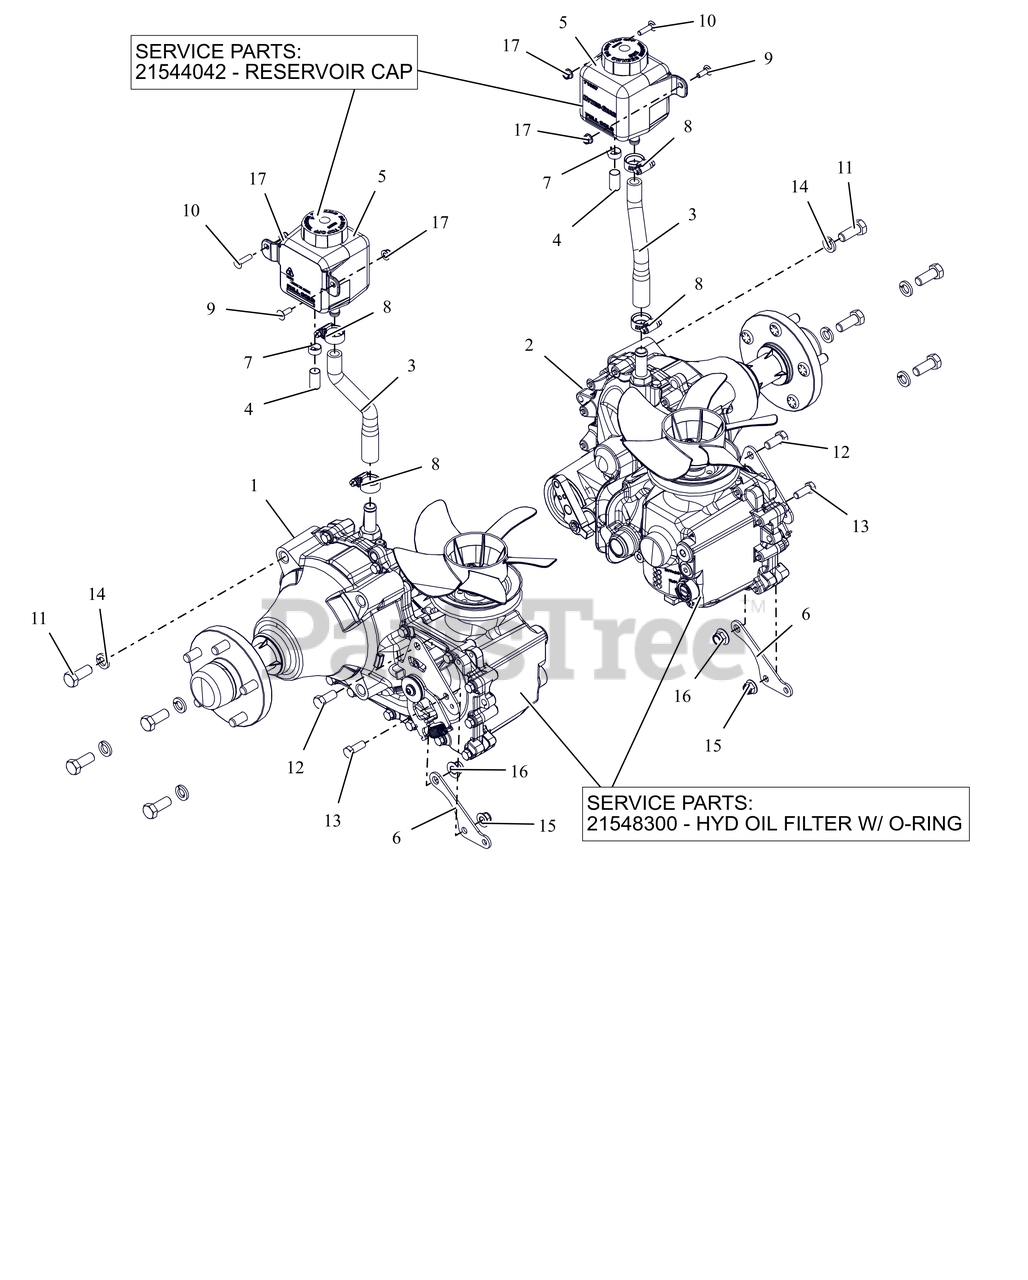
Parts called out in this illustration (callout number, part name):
1	TRANS, RH HG ZT-5400
1	FILTER,HYD OIL W/ORING ZT-54OO
2	TRANS, LH HG ZT-5400
2	FILTER,HYD OIL W/ORING ZT-54OO
3	HOSE,PT200/400 TRANS OVERFLOW
4	CAP, .50 BARBED FITTING
5	TANK, HYDRO OVERFLOW 700 ML
5	CAP, HYDRO RESERVOIR REPLAC.
6	DRV CNTRL LINKAGE MTG BRKT-BLK
7	CLAMP, .62 SPRING
8	CLAMP,.88 DIA. HOSE
9	@BLT-RDHDSQNK .25-20X.75 G5YZ
10	@BLT-RDHDSQNK .25-20X1.00 G5YZ
11	@BLT-HEX .50-13X1.25 GR5 YWZC
12	@BLT-HEX .44-14X1.00 GR5 YWZC
13	@BLT-HEX .38-16X1.00 GR5 YWZC
14	@WSHR-LK .50X.125 REG YWZC
15	@NUT-LK-NYL-FLG .38-16 YWZC
16	@NUT-LK-NYL-FLG .44-14 YWZC
17	@NUT-LK-NYL-FLG .25-20 YWZC
